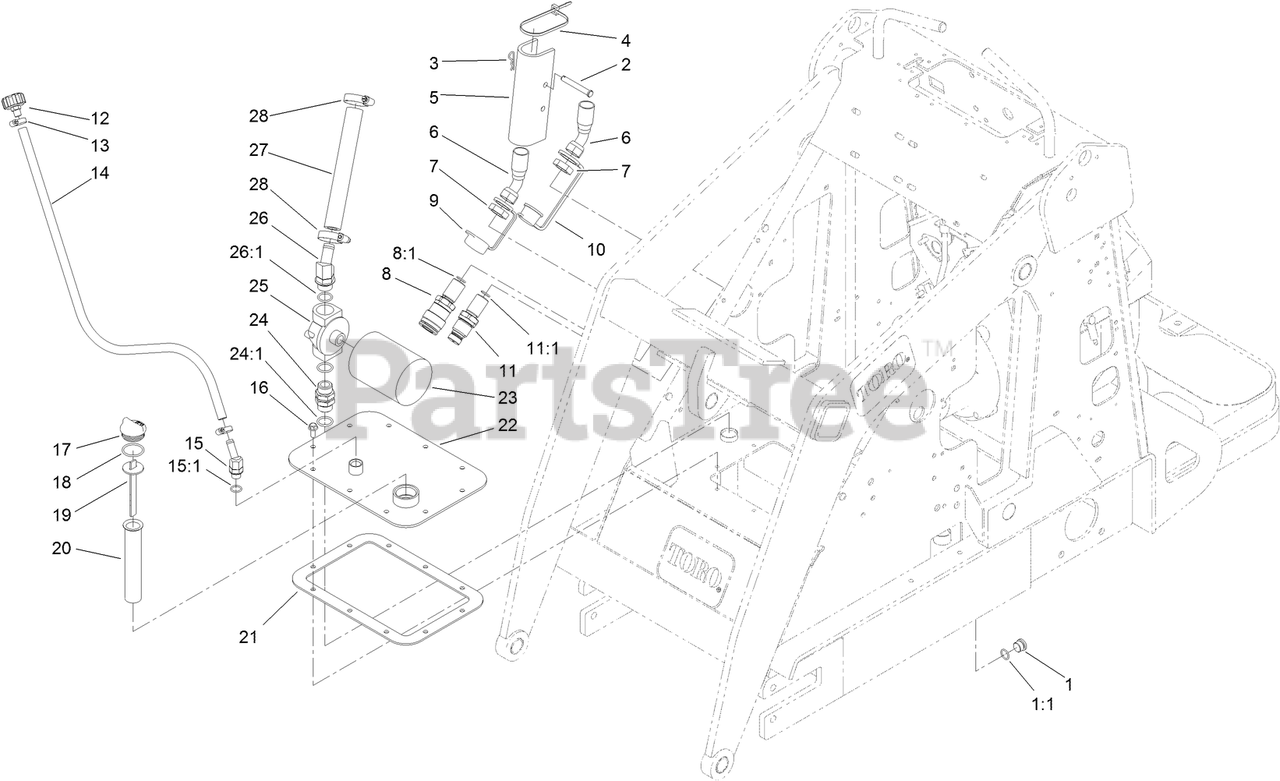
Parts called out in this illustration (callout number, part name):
1	PLUG-HEX
1:1	O-RING
2	PIN-CLEVIS
3	PIN-HAIR
4	TIE-CABLE
5	LOCK-CYLINDER
6	HOSE-HYD
7	NUT-LOCK, BULKHEAD
8	BULKHEAD COUPLER ASM
8:1	O-RING
9	CAP-DUST, COUPLER
10	CAP-DUST, NIPPLE
11	BULKHEAD NIPPLE ASM
11:1	O-RING
12	BREATHER
13	CLAMP-HOSE
14	HOSE-VENT
15	FITTING-HYD, 45 DEG
15:1	O-RING
16	SCREW
17	PLUG-PLASTIC
18	O-RING
19	DIPSTICK-OIL
20	FILTER-SCREEN
21	GASKET-COVER
22	COVER
23	FILTER-OIL, TRANSMISSION
24	FITTING-THREAD, STRAIGHT
24:1	O-RING
25	HEAD-FILTER
26	ELBOW-45 DEG
26:1	O-RING
27	HOSE-SUCTION, HYD
28	CLAMP-HOSE
